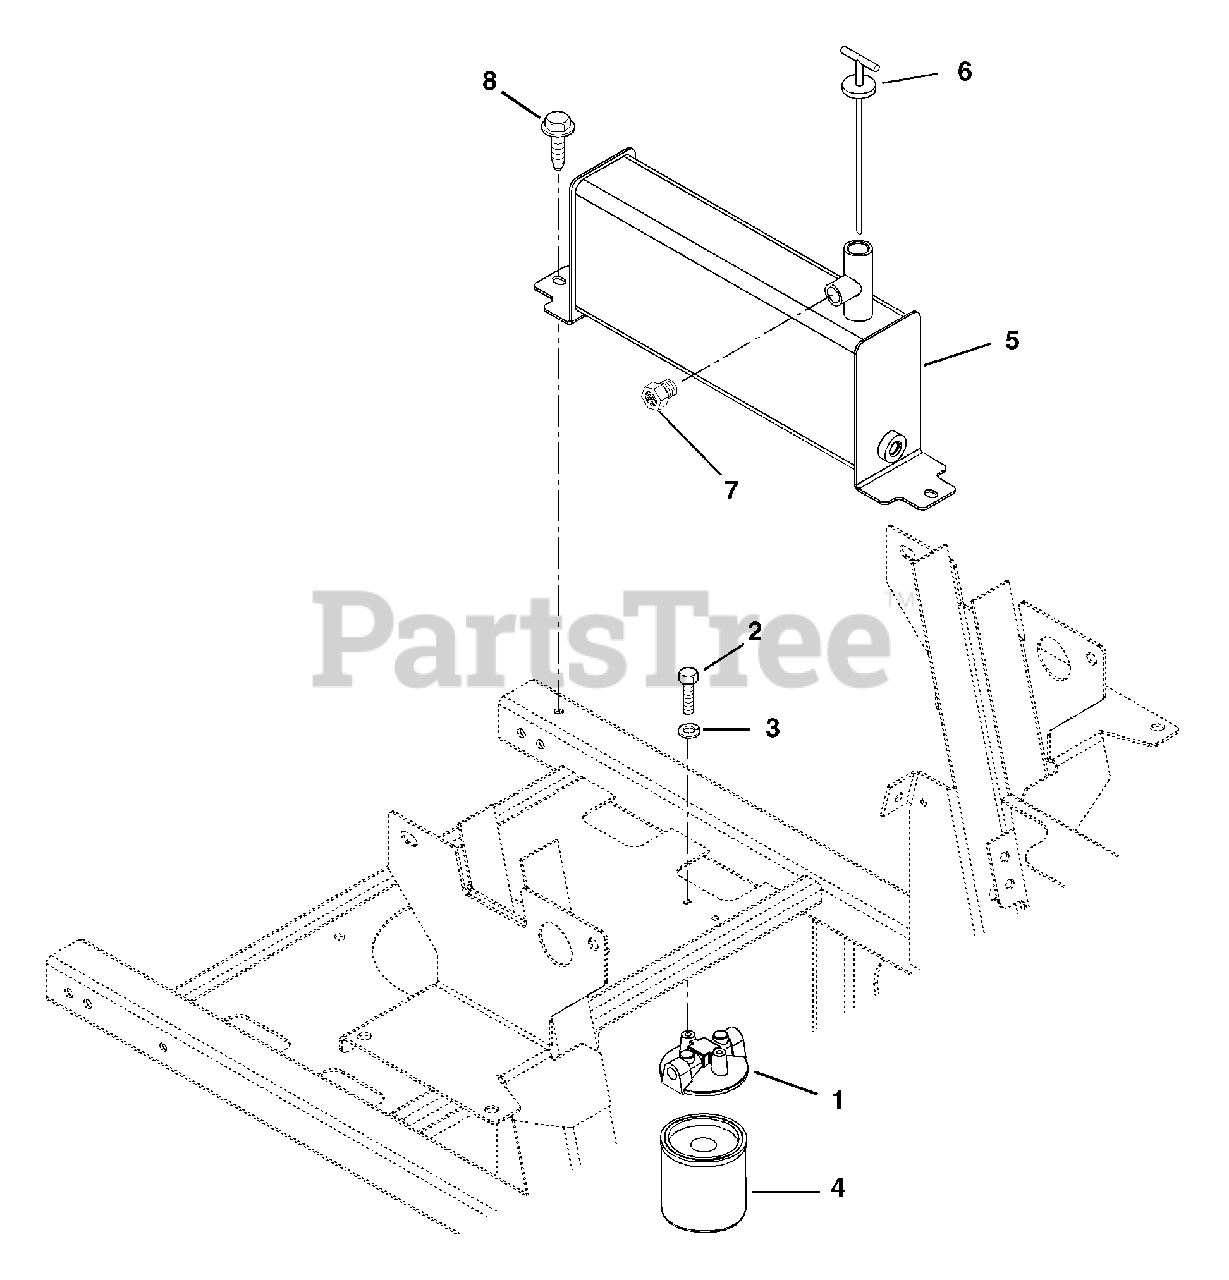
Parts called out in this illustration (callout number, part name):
1	Head-Filter
2	Bolt-Hex .25 - 20 x .50 Grade 5
3	Washer-Locking .25 x .062
4	Oil Filter
5	Tank-Hydraulic Weldment
6	Hydraulic Tank Dipstick
7	Plug-Breather .38
8	Screw-Tapping .38 - 16 x .75 Hex Washer Head
